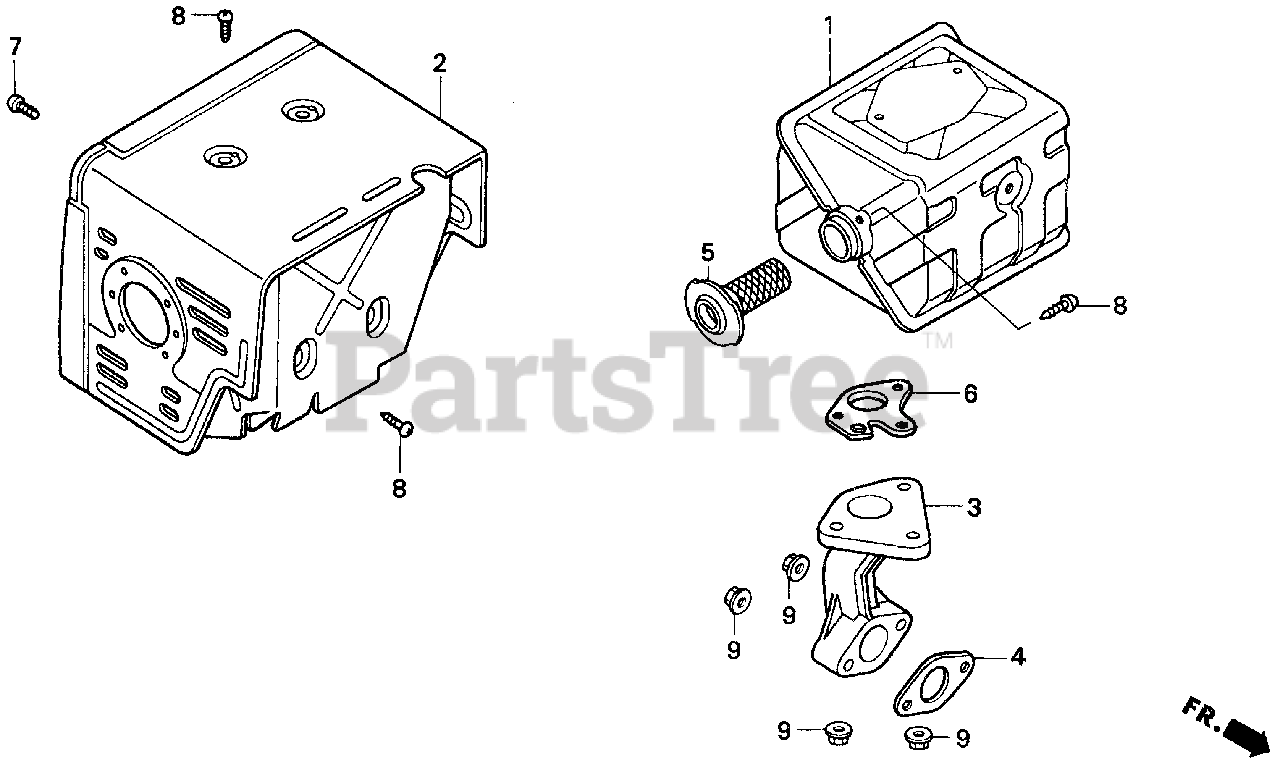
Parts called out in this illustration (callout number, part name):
1	MUFFLER (100DB) (SILENT)
1	MUFFLER (100DB)
2	PROTECTOR, MUFFLER
3	PIPE, EX.
4	GASKET, EX. PIPE
4	GASKET, EX. PIPE (WACKER)
5	ARRESTER, SPARK
6	GASKET, MUFFLER (ARRESTER)
7	SCREW, TAPPING (6X10)
8	SCREW, TAPPING (5X8)
9	NUT, FLANGE (8MM)
